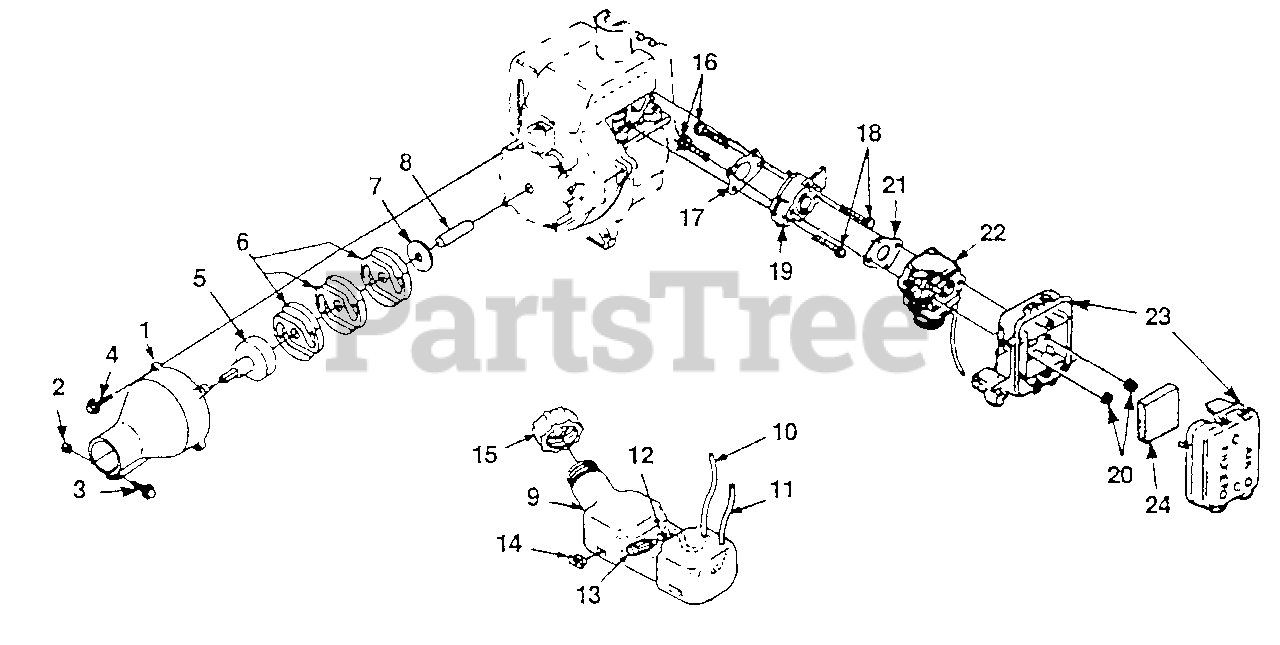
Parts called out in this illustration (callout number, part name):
1	TUBE ADAPTOR KIT
2	NUT-Hex (10-24)
3	SCREW-Sems Hex Hd. (10-24 X 1 1/4")
4	SCREW-Sems Hex Hd. (10-24 X 7/8")
5	DRUM & CONNECTOR
7	WASHER-Clutch
8	SPACER
9	FUEL TANK
10	TUBING-Rubber (4 1/4")
11	TUBING-Rubber (7 1/2")
12	CLAMP-Wire
13	FILTER-Fuel
14	BUMPER-Rubber
15	CAP-Fuel Tank
16	SCREW-Hex Hd. (10-24 X 2 1/4")
17	GASKET-Heat Dam
18	SCREW-Taptite, Torx (10-24 X 1")
19	HEAT DAM
20	NUT-Hex (10-24)
21	GASKET-Carburetor
22	CARBURETOR (Walbro)
23	AIR FILTER KIT
24	FILTER-Air
